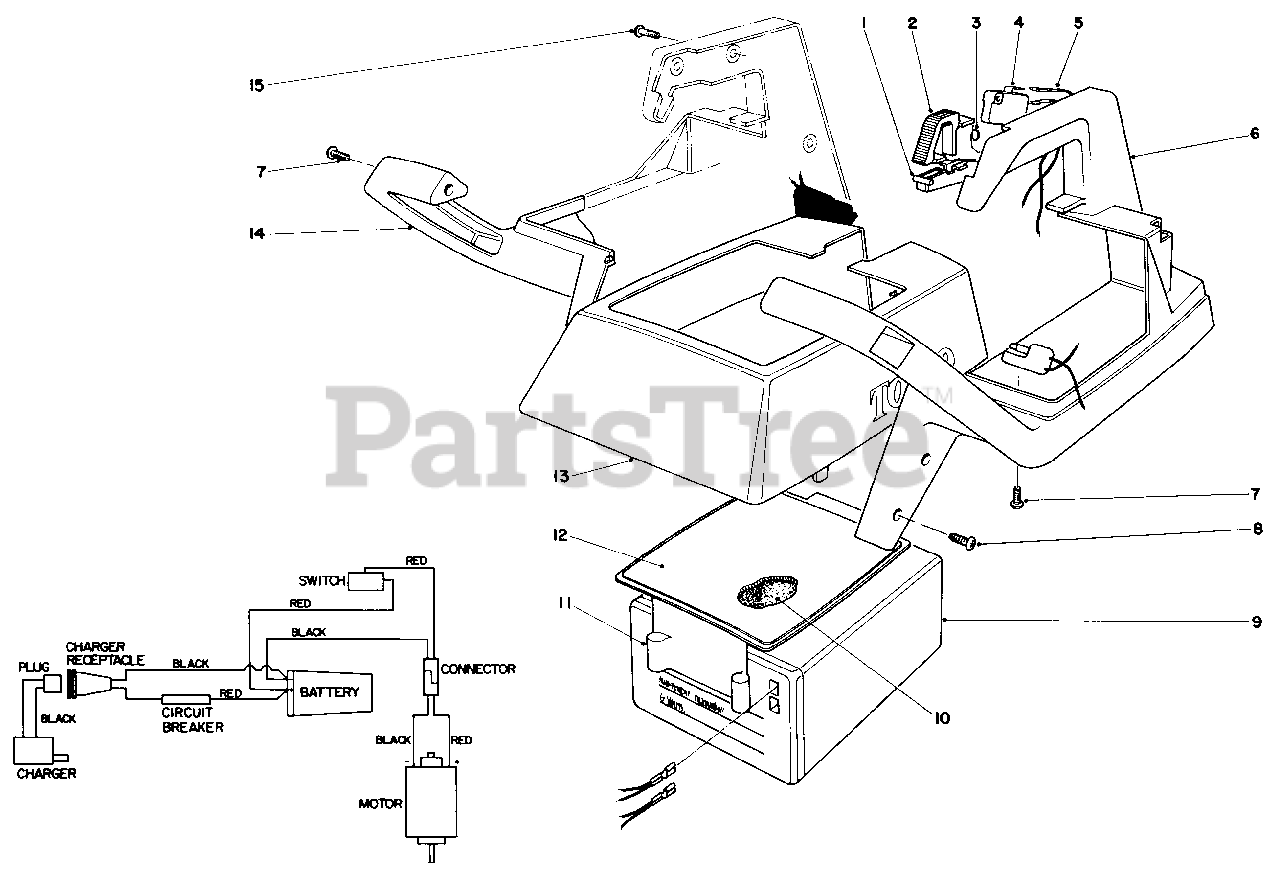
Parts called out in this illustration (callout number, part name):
2	Release-Trigger
5	Wiring Harness
6	Handle & Battery Case L.H.
7	Screw
8	Screw-Self Tapping
10	Pad-Foam
11	Panel-Control
12	Decal-Control Panel
14	Handle & Battery Case R.H.
